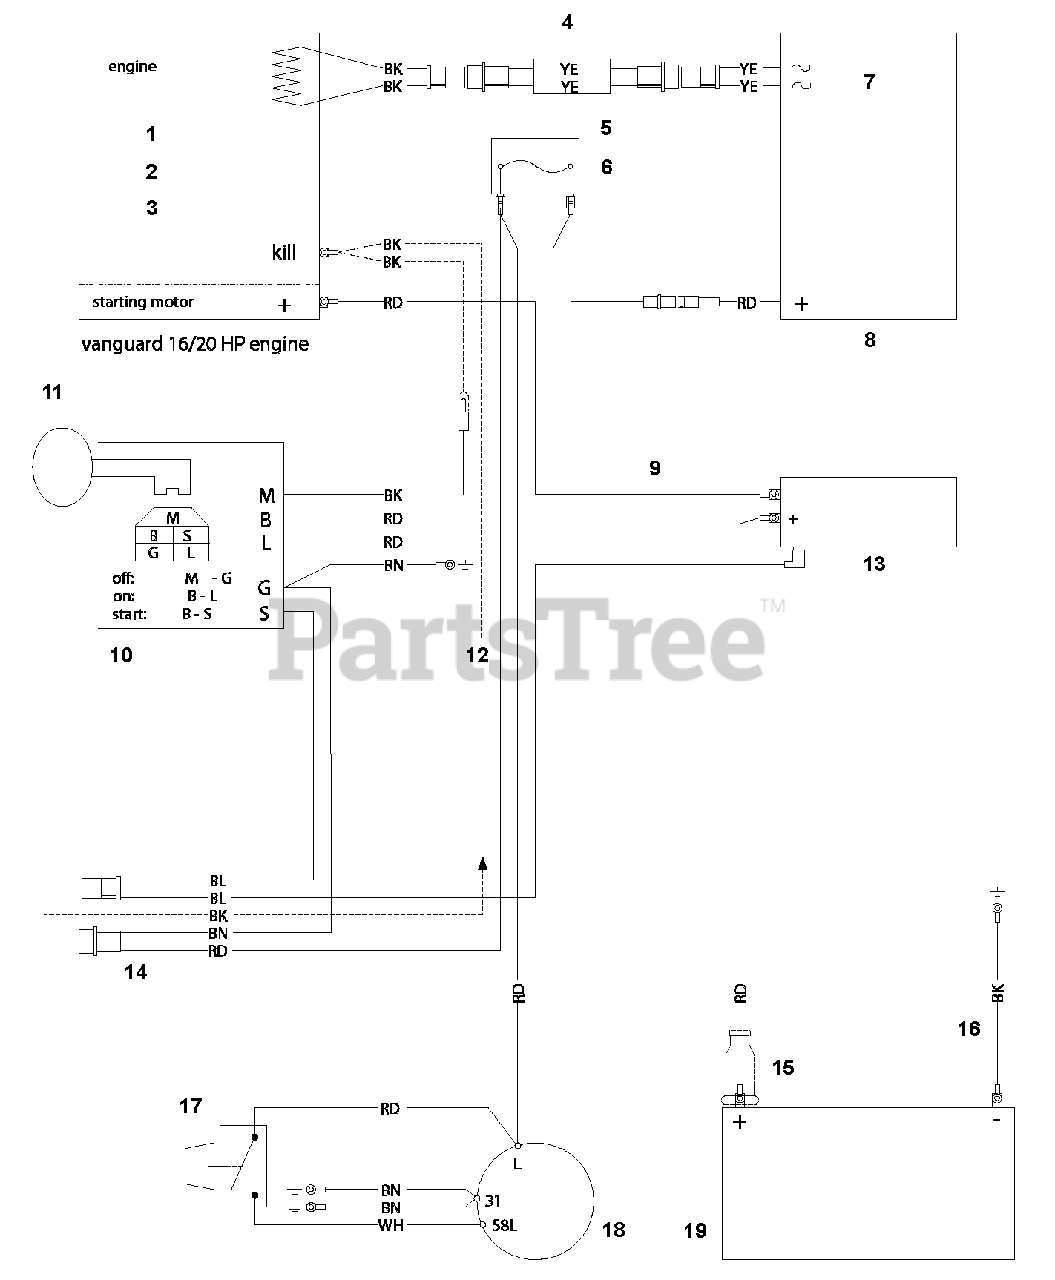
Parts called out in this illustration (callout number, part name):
1	Alternator
2	Flywheel 16HP
3	Flywheel
5	Fuse Box
6	15A, Fuse
7	Voltage Regulator
8	Regulator, 691.185
9	Cable Red
10	Assembly, Starter Switch
11	Assembly, Key
12	Cable Harness
14	Harness, Wiring
16	Cable Black
18	Plug Socket, D72577 12/7A
19	Battery, 12V 18AH
